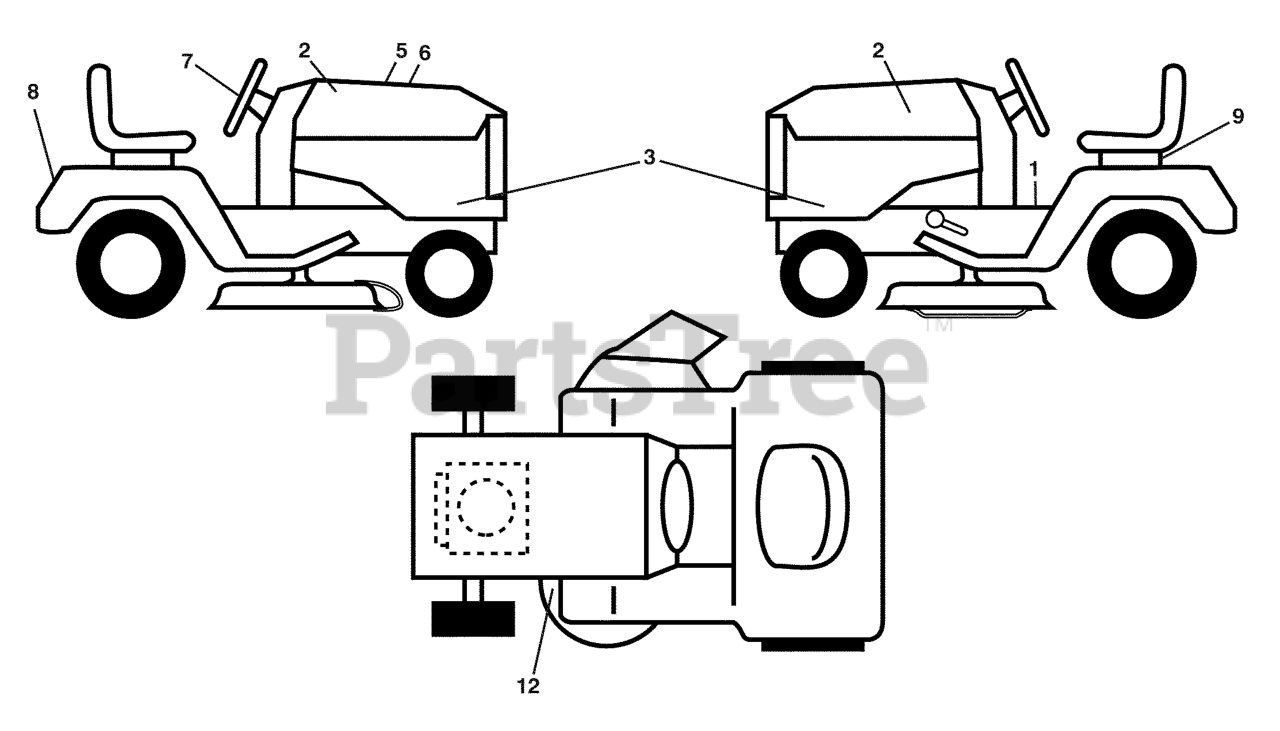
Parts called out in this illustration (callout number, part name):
1	DECAL.WARN.START.INSTRUCTIONS
2	DECAL.HOOD.LOGO.HUSQVARNA
3	DECAL, HOOD PANEL SD
5	DECAL HOOD CUST. RESP.
6	DECAL.RPL.KH.SV600.TLW.46"
7	DECAL.WHEEL.STRG.LGN.H
8	DECAL.FENDER
9	DECAL BTRY SYMBOLS
12	DECAL V BELT SCHEMATIC
